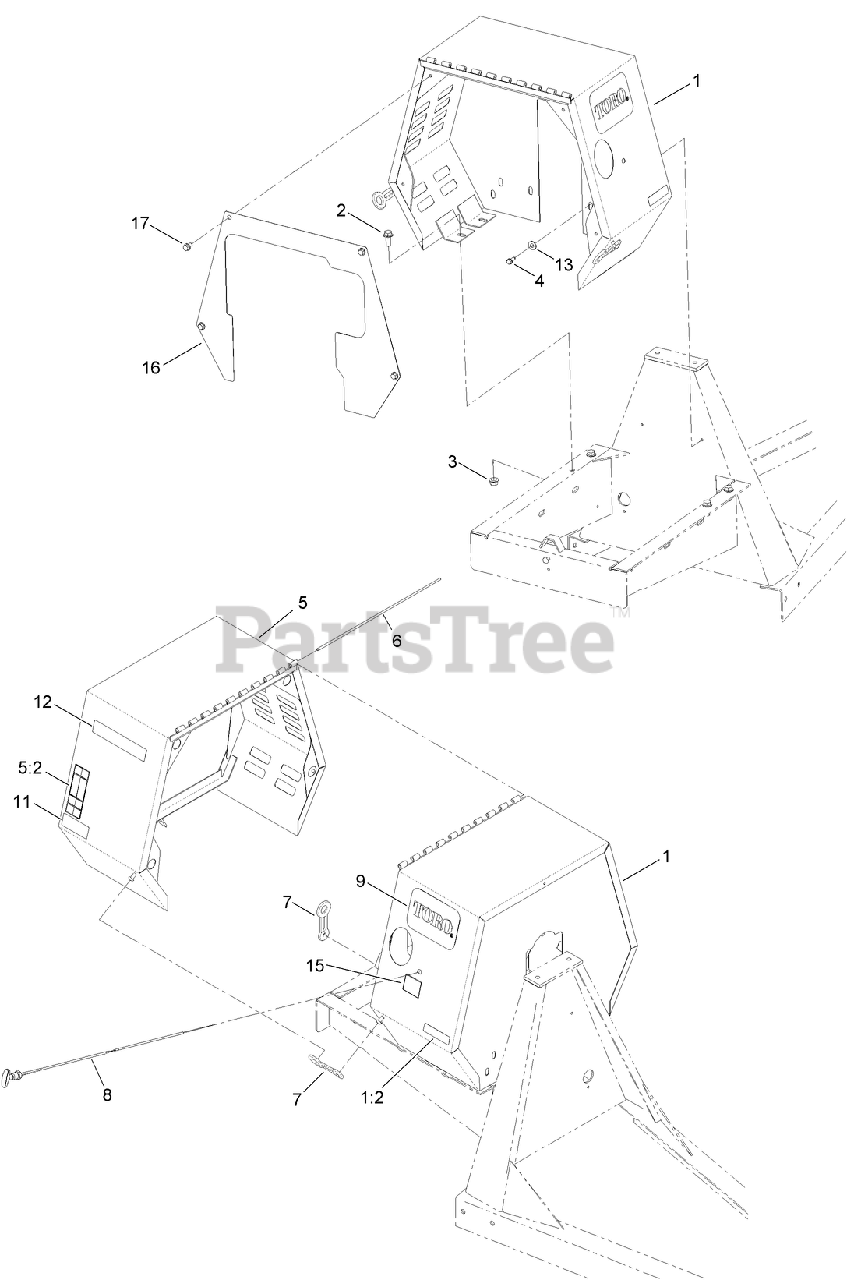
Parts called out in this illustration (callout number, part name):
1	STATIONARY COWL ASM
1:2	DECAL-ARRESTER, SPARK
2	SCREW-HHF
3	NUT-LOCK
4	SCREW-HWHTF
5	MOVABLE COWL ASM
5:2	DECAL-WARNING
7	LATCH-RUBBER
8	CABLE-THROTTLE
9	DECAL
13	WASHER-FLAT
15	DECAL-THROTTLE, DIESEL
16	PLATE-GUARD, DRIVE
17	SCREW-HWH
